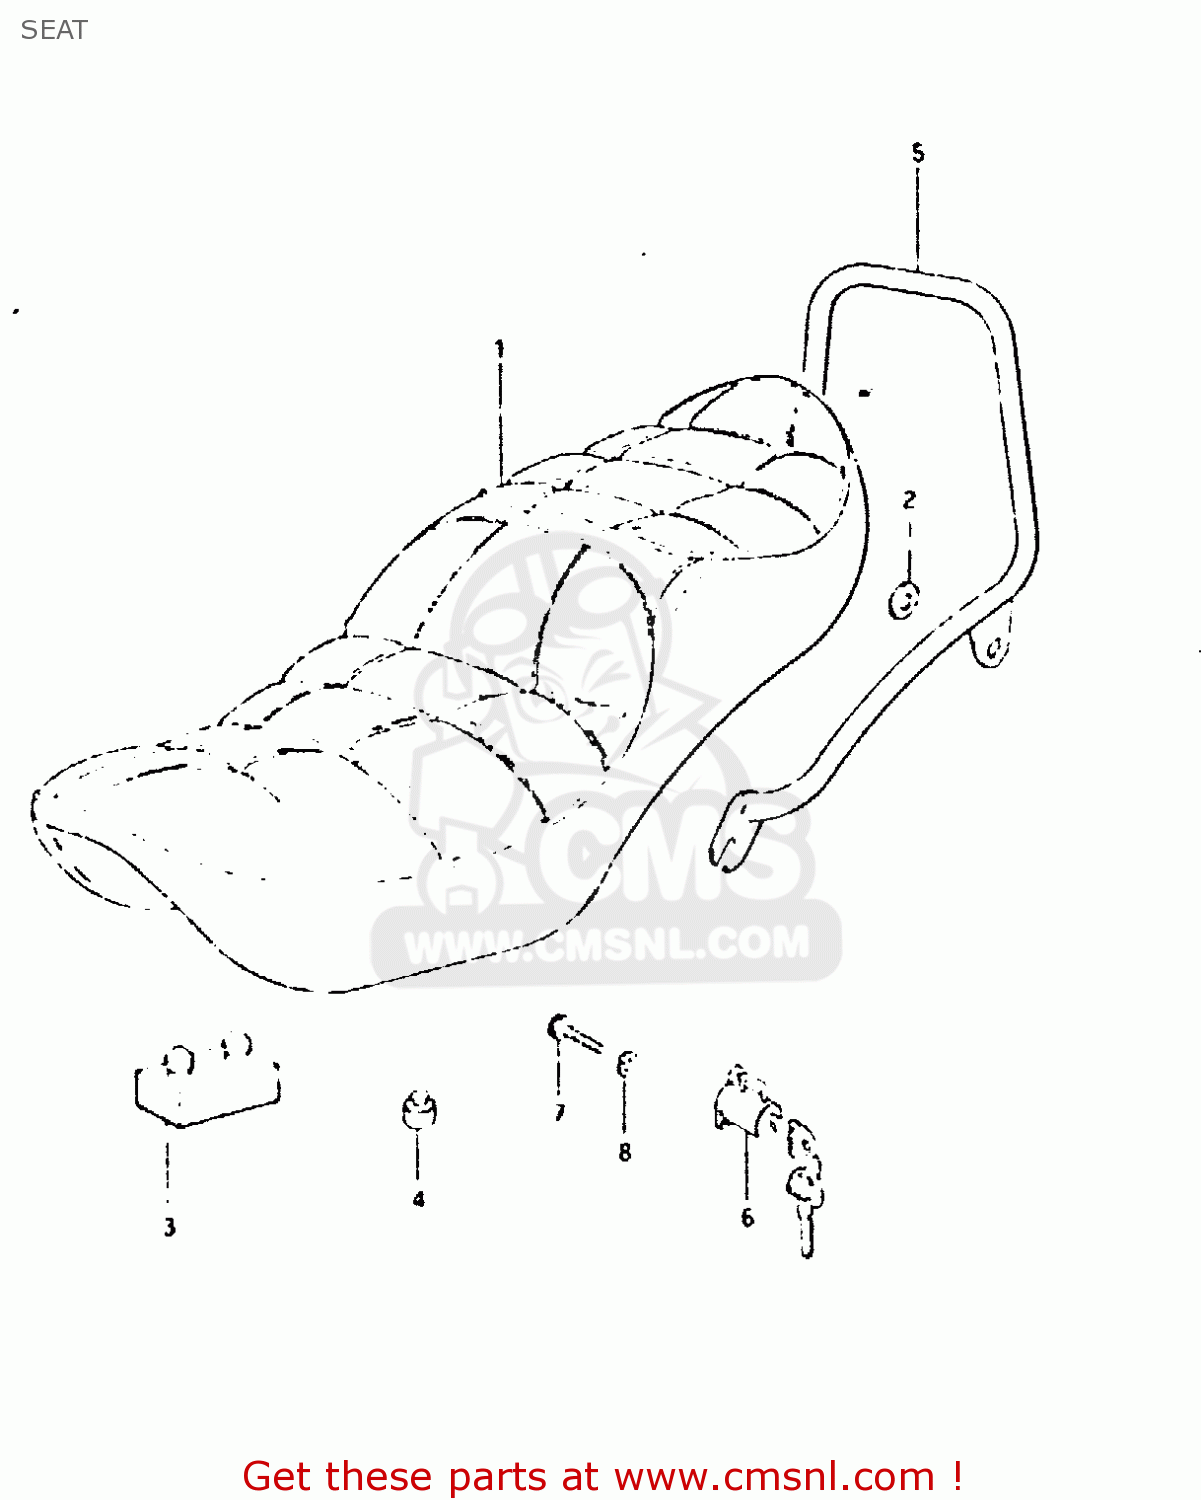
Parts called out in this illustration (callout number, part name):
1	SEAT ASSY (BLACK)
3	CUSHION
4	CUSHION
5	HANDLE,PILLION RIDER
6	LOCK ASSEMBLY,HELMET
7	BOLT 6X11
8	LOCK WASHER
